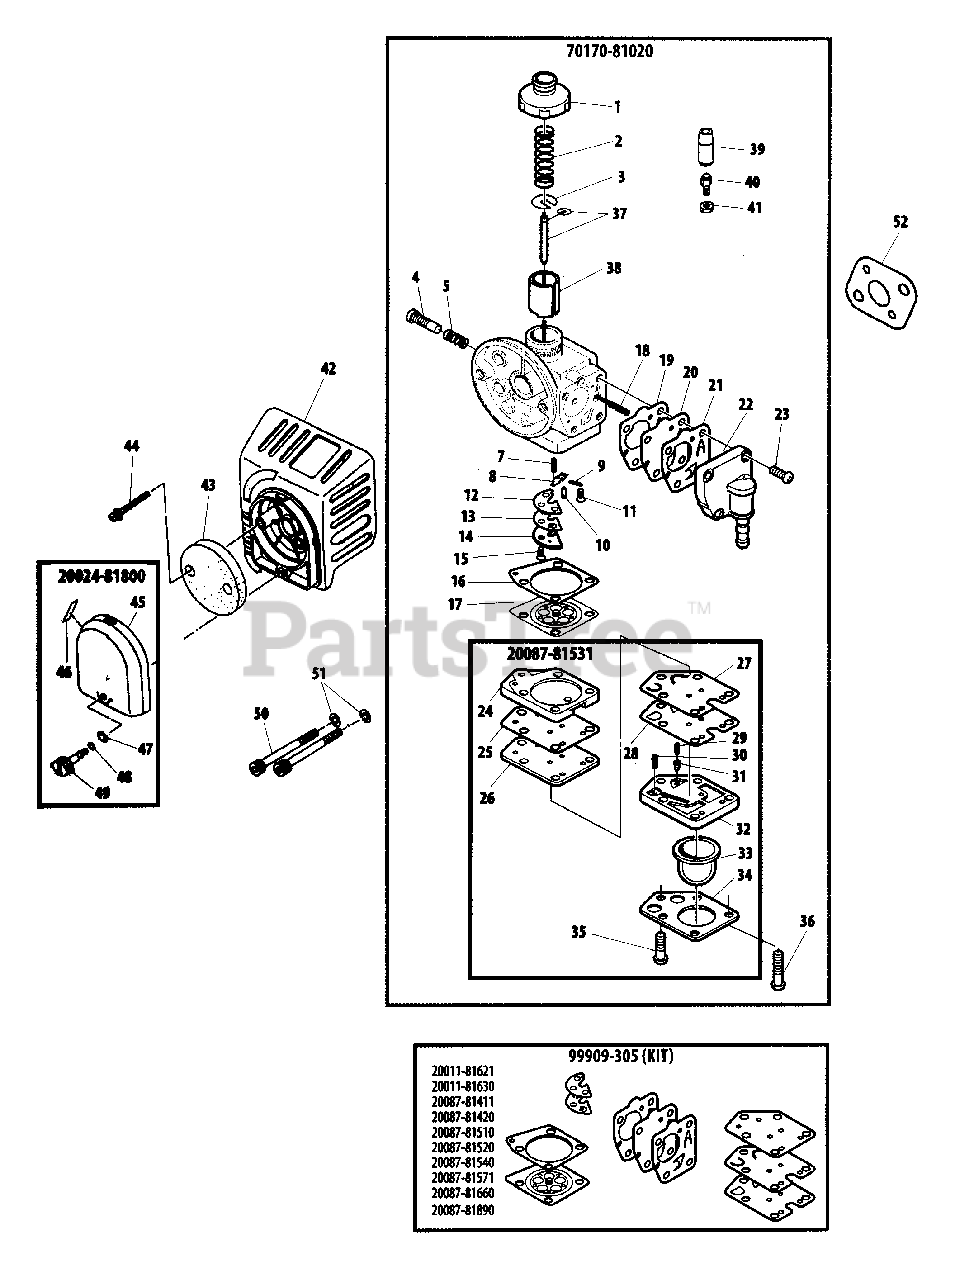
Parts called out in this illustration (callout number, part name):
1	CAP, CARBURETOR
2	SPRING
3	RETAINER
4	SCREW, IDLE ADJUST
5	SPRING
7	SPRING
8	LEVER, METERING
9	PIN, METERING LEVER
10	VALVE, INLET NEEDLE
11	SCREW, METERING LEVER PIN
12	GASKET
13	VALVE, CHECK
14	PLATE
15	SCREW, METERING LEVER PIN
16	GASKET, METERING
17	DIAPHRAGM, METERING
18	SPRING
19	GASKET, METERING
20	DIAPHRAGM, METERING
21	VALVE, PUMP
22	BODY, PUMP
23	SCREW
24	BASE, PURGE
25	GASKET
26	PLATE, PUMP
27	DIAPHRAGM
28	GASKET
29	SPRING, RETURN
30	SPRING
31	VALVE
32	COVER, PUMP
33	BULB, PURGE
34	PLATE
35	SCREW
36	SCREW
37	NEEDLE, JET
38	SLIDE VALVE
39	GROMMET
40	NUT, CABLE ADJUST
41	LOCKNUT
42	CASE, AIR FILTER
43	FILTER, AIR
44	SCREW - 4X25
45	COVER, AIR FILTER
46	LABEL - CHOKE
47	WASHER - CONICAL
48	O-RING
49	THUMBSCREW
50	SCREW - 5X65
51	LOCKWASHER - 5
52	GASKET, INTAKE
20024-81800	AIR FILTER COVER ASSY
20087-81531	PRIMER PUMP ASSY
70170-81020	CARBURETOR
99909-305	DIAPHRAGM/GASKET KIT
